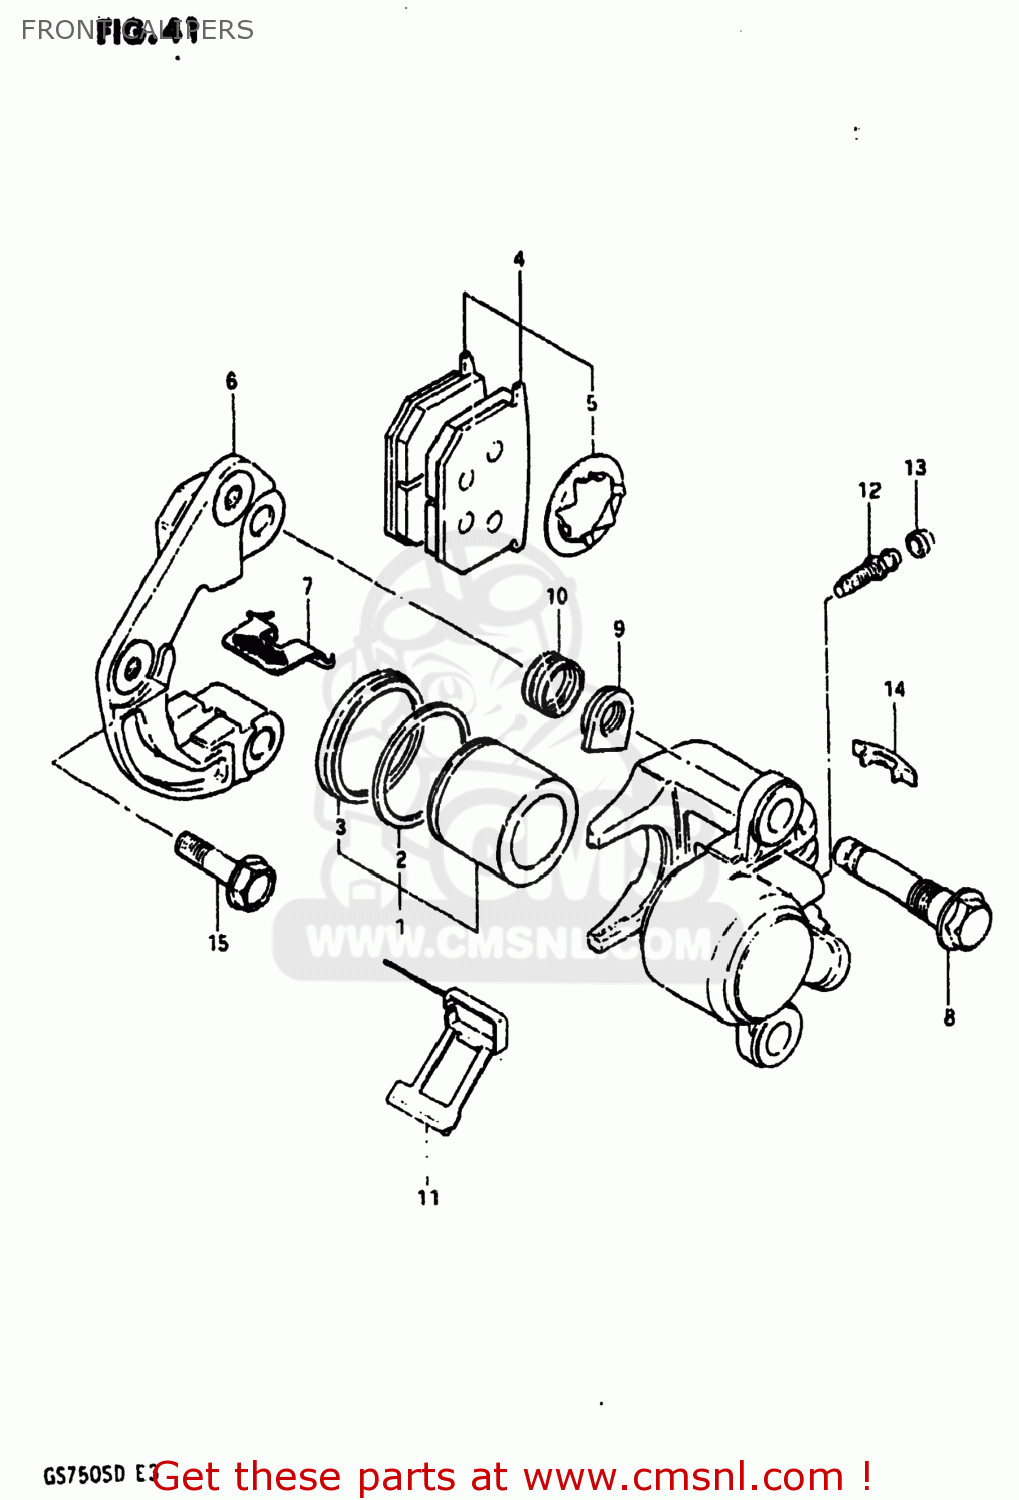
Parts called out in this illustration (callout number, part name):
0	CALIPER ASSEMBLY,LEFT
1	PISTON SET
2	SEAL,PISTON
3	BOOT,PISTON
4	PAD & SHIM SET (MCA)
5	SHIM,PAD
6	HOLDER,CALIPER,LEFT
7	PAD,GUIDE
8	AXLE
9	NUT,CALIPER AXLE
10	BOOT
11	SPRING
12	BREATHER
13	CAP,BLEEDER PL
14	COVER,INDICATOR
15	BOLT 10X37
